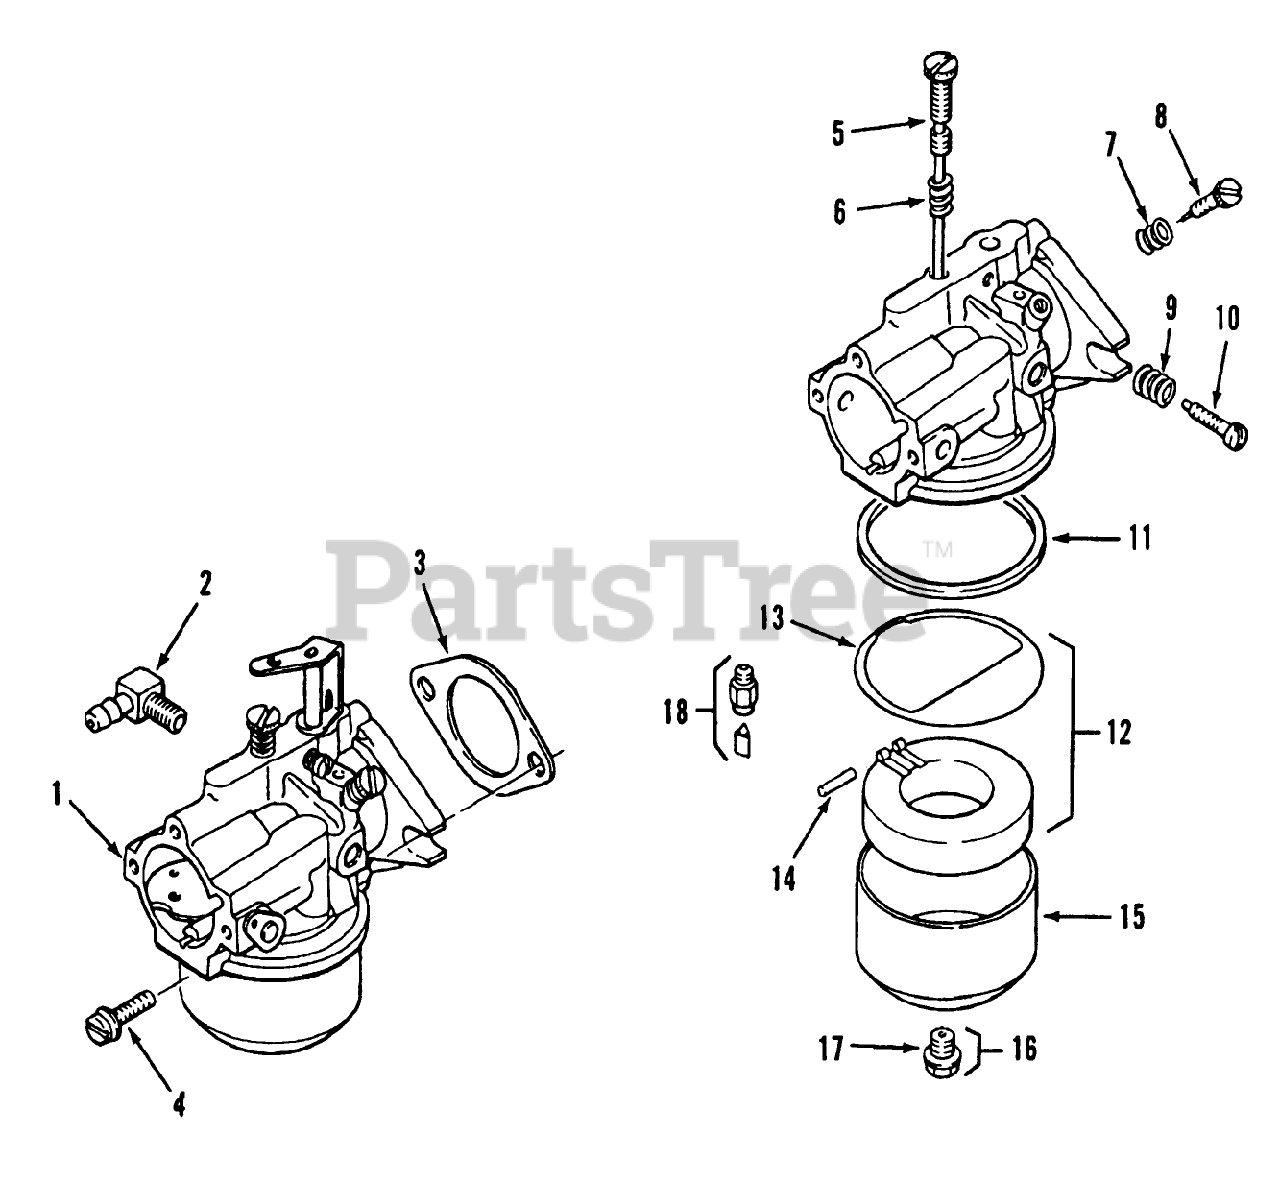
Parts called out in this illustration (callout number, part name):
1	KOHLER 47-853-09
2	KOHLER 25-155-02
3	KOHLER 47-049-01
4	KOHLER X-770-1
5	KOHLER 235415
5	KOHLER 47-103-01
6	KOHLER 200383
7	KOHLER 200380
8	KOHLER 235006
8	KOHLER 275231
9	KOHLER 232555
10	KOHLER 232556
11	KOHLER 200375
12	KOHLER 25-757-03
13	KOHLER 25-041-02
14	KOHLER 200376
15	KOHLER 235448
16	KOHLER 47-100-06
17	KOHLER 200372
